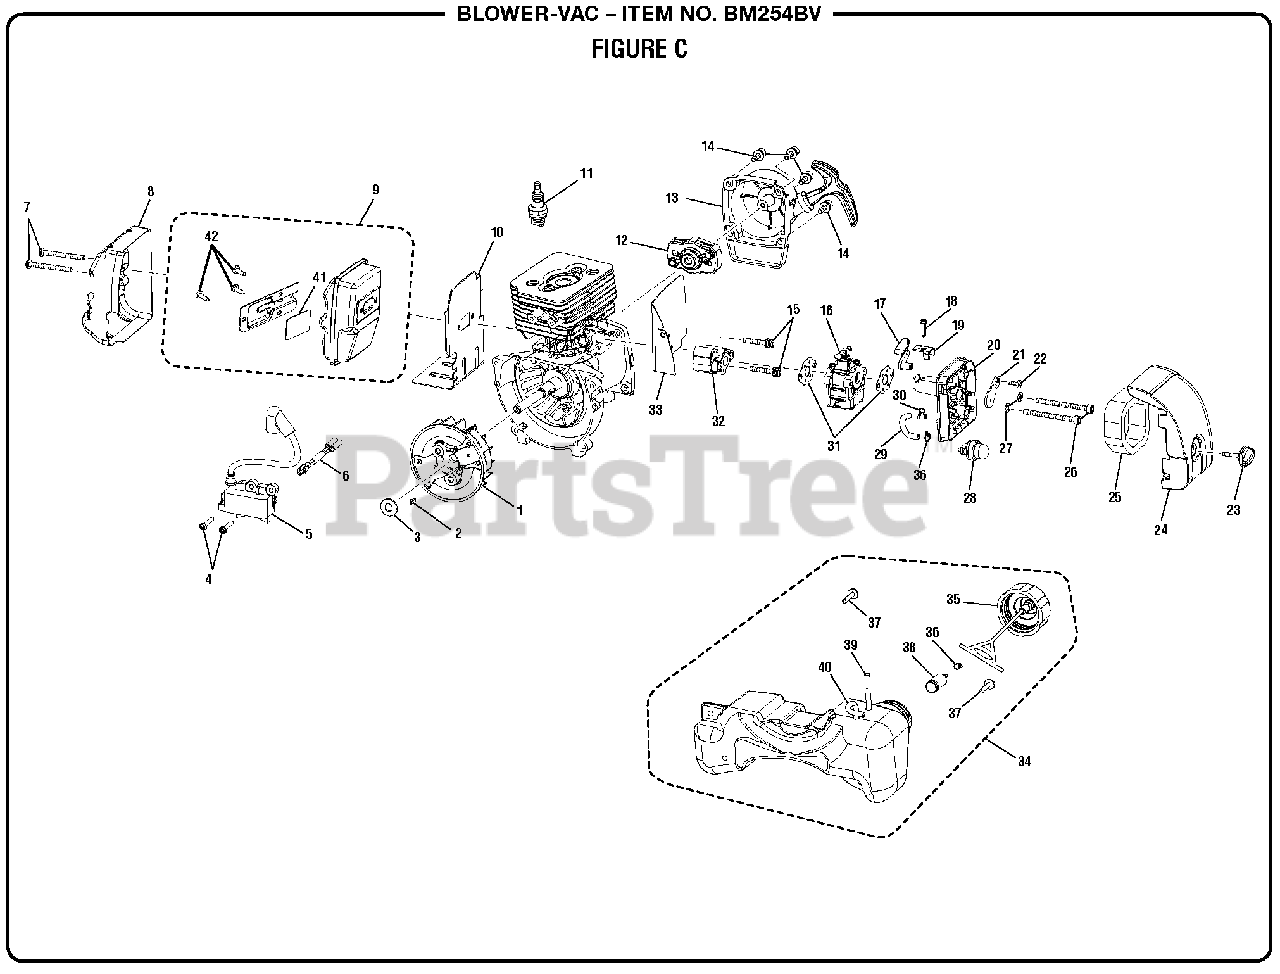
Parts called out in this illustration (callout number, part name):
2	Woodruff Key
3	Washer (ID9.8 x OD30 x 3t)
4	Screw w/Washers (M4 x 22 mm, T25 Torx Soc. Hd.)
5	Ignition Coil Assembly
6	Ignition Lead Assembly
7	Cap Screw (M5 x 50 mm, T25 Torx Soc. Hd.)
8	Heat Shield
9	Muffler Assembly
10	Muffler Gasket
11	Spark Plug (Champion RC6Y)
12	Pulley Assembly
13	Recoil Starter Assembly w/Label
14	Cap Screw w/Washers (M5 x 16 mm, T25 Torx Soc. Hd.)
15	Screw w/Washers (M5 x 31 mm, T20 Torx Pan Hd.)
16	Carburetor Assembly
17	Choke Lever
18	Screw (M4 x 16 mm, T20 Torx Pan Hd.)
19	Retaining Clip
20	Air Box Case
21	Choke Plate
22	Screw (M4 x 12 mm, T20 Torx Pan Hd.)
23	Knob
24	Air Box Cover w/Label
25	Air Filter
26	Cap Screw (M5 x 60 mm, T25 Torx Soc
27	Washer (ID5 x OD12 x 0.80t)
28	Primer Bulb Assembly
29	Hose (51 mm)
30	Hose Clip
31	Carburetor Gasket
33	Heat Dam Gasket
34	Fuel Tank and Cap Assembly
35	Fuel Cap Assembly
36	Hose Clip
37	Screw (10-14 x 7/8 in., T25 Torx Pan Hd.)
38	Fuel Filter
39	Rubber Tubing (225 mm, Low Permeation)
40	Rubber Tubing (114 mm)
41	Screen
42	Screw (6-20 x 1/4 in., T20 Torx Pan Hd. S.T.)
